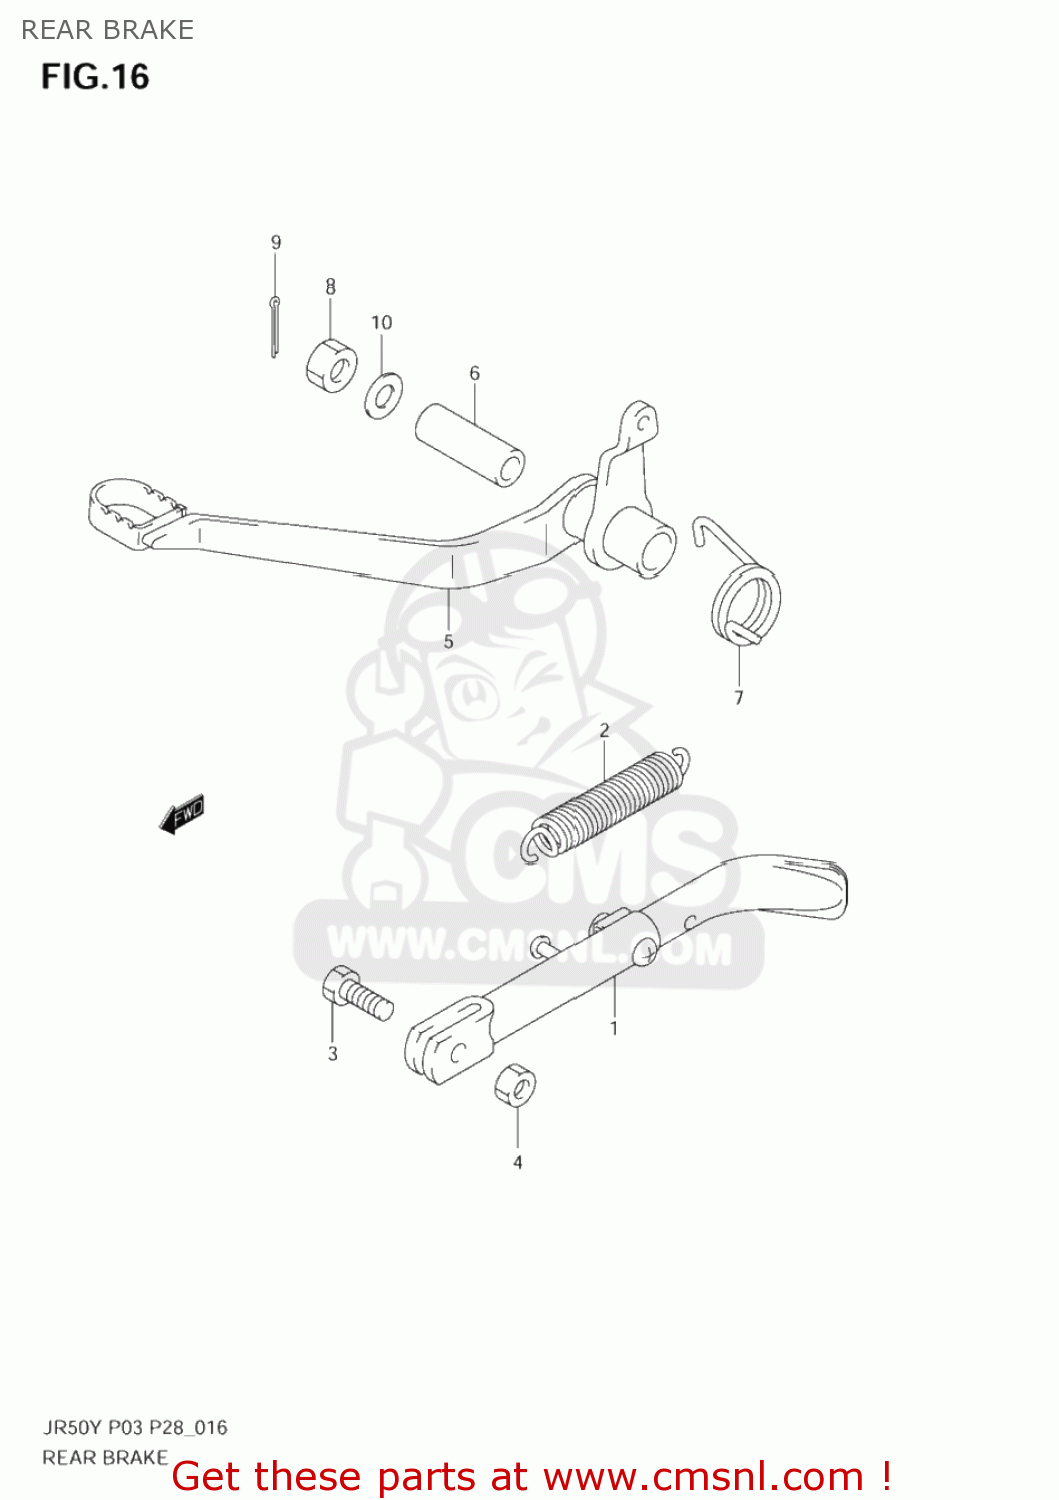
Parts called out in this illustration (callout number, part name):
1	STAND,PROP
2	SPRING
3	BOLT 8X22
4	NUT
5	PEDAL,BRAKE
6	SPACER,BRAKE PEDAL
7	SPRING,BRAKE PEDAL RETURN
8	NUT
9	PIN 25X20
10	WASHER(10.5X22X1.6)
